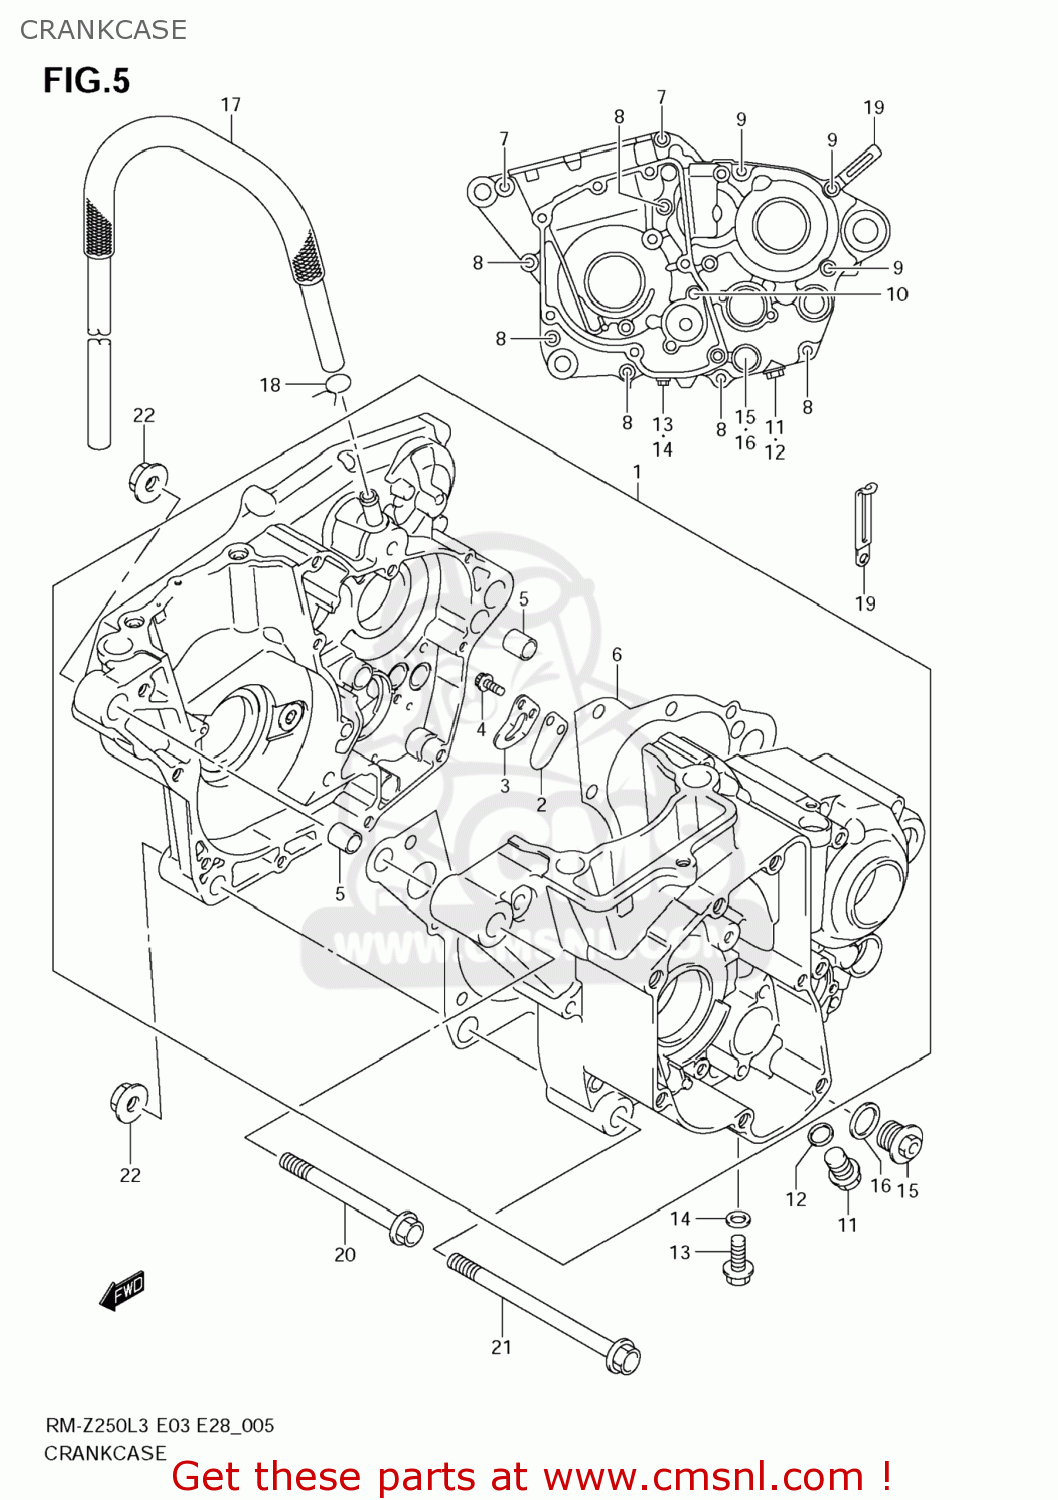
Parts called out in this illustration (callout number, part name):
1	CRANKCASE ASSY
2	VALVE,CRANKCASE REED
3	STOPPER,CRANKCASE REED VALVE
4	BOLT
5	PIN(10.4X13X18)
6	GASKET,CRANKCASE (NAS)
7	BOLT
8	BOLT
9	BOLT
10	BOLT
11	PLUG,12X20
12	GASKET(12.1X16.2X3.7) (NAS)
13	BOLT(8X20)
14	GASKET(7.8X13.5X1.2) (NAS)
15	CAP,ENG OIL STRAINER
16	GASKET(16X22X2) (NAS)
17	HOSE,BREATHER
18	CLIP
19	CLAMP(L:45)
20	BOLT(10X80)
21	BOLT(10X120)
22	NUT
